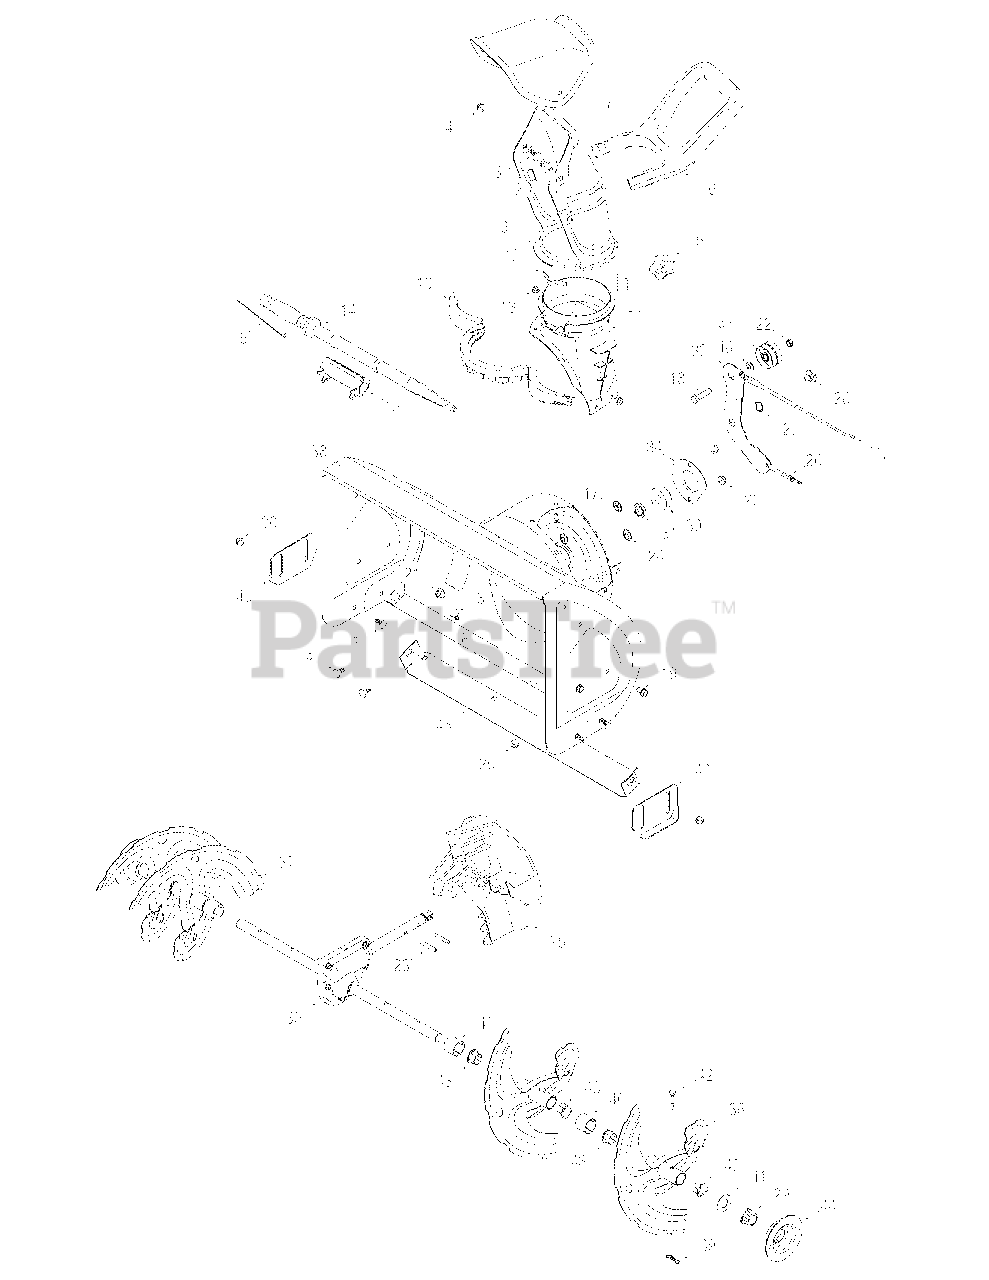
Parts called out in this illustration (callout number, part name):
1	Chute Assembly
2	Carriage Bolt 5/16-18 x 1.0"
3	Carriage Bolt 5/16-18
4	Flange Lock Nut, 5/16-18
5	Star Knob 5/16-18
6	Chute Handle
7	Upper Chute
8	Flat Washer .349 x .879 x .063
9	Lower Chute
10	Chute Ring
11	Chute Adapter 5" Dia.
12	Chute Adjustment Spring
13	Flange Lock Nut 1/4-20
14	Clean-out Tool
15	Clean-out Tool Mount
16	Cable Tie
17	Carriage Screw 1/4-20 x 0.62"
18	Hex Bolt 3/8-16 x 1.50"
19	AB Screw 5/16-18 x .625
20	Flange Lock Nut, 5/16-18
21	Flange Lock Nut, 3/8-16
22	Jam Lock Nut 3/8-16
23	Spiral Pin
24	Push On Nut
25	Impeller
26	Extension Spring
27	Wave Washer
28	Shoulder Screw 3/8-16
29	Hex Flange Bearing
30	Ball Bearing
31	Spacer
32	Flat Idler
34	Bearing Housing
35	Auger Gearbox Assembly
40	Spacer, 1.25 x.75 x 1.00
41	Flat Washer
42	Shear Pin,.25 x 1.50
43	Flange Bushing
47	Auger Cable
48	Flat Washer
